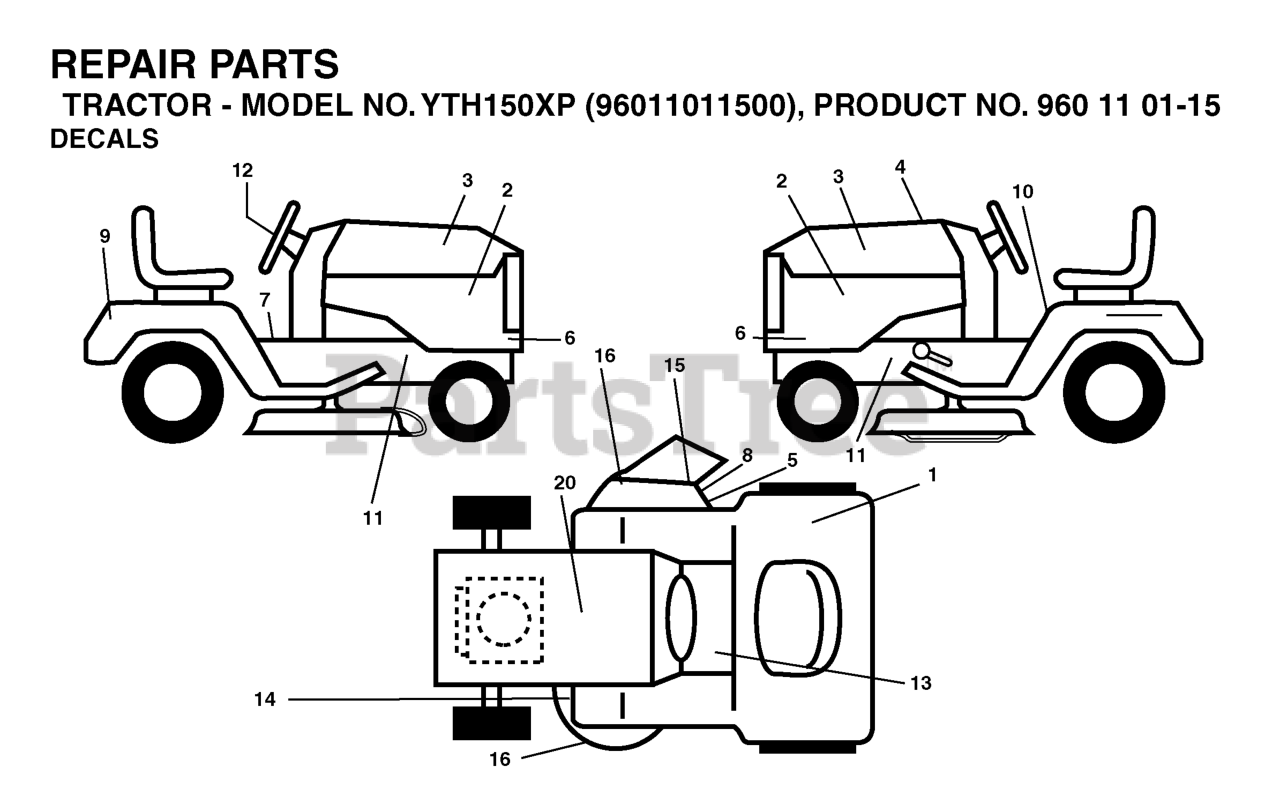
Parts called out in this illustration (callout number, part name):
1	Decal, Fender 100 DB/CE
2	DECAL.HOOD.HUSQVARNA.INTERNATI
5	DECAL, DEFLECT WARNING
7	DECAL PARK BRAKE
8	DECAL.INTERNATIONL.CUTFINGER
10	LABEL
12	DECAL.STEERING.HUSQ.BLUE
13	DECAL
14	DECAL V BELT SCHEMATIC
15	DECAL DECK "B" 42"
20	DECAL BTRY SYMBOLS
